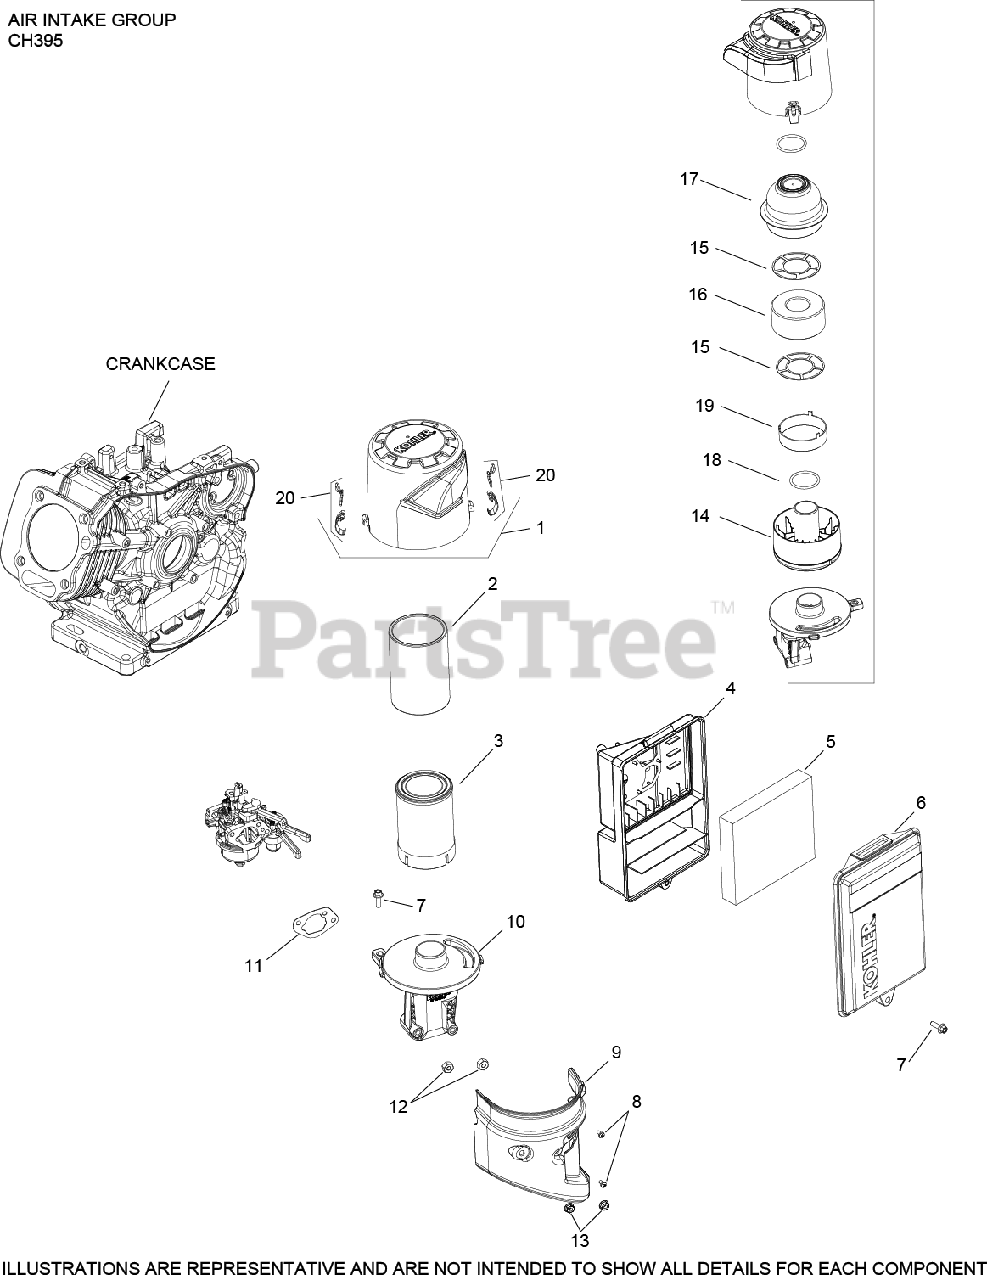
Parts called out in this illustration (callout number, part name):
4	KIT, AIR CLEANER BASE ASSEMBLY USE 17 094 67-S
5	ELEMENT, AIR FILTER
6	COVER, AIR CLEANER
13	NUT, HEX FLANGE LOCK (M6)
